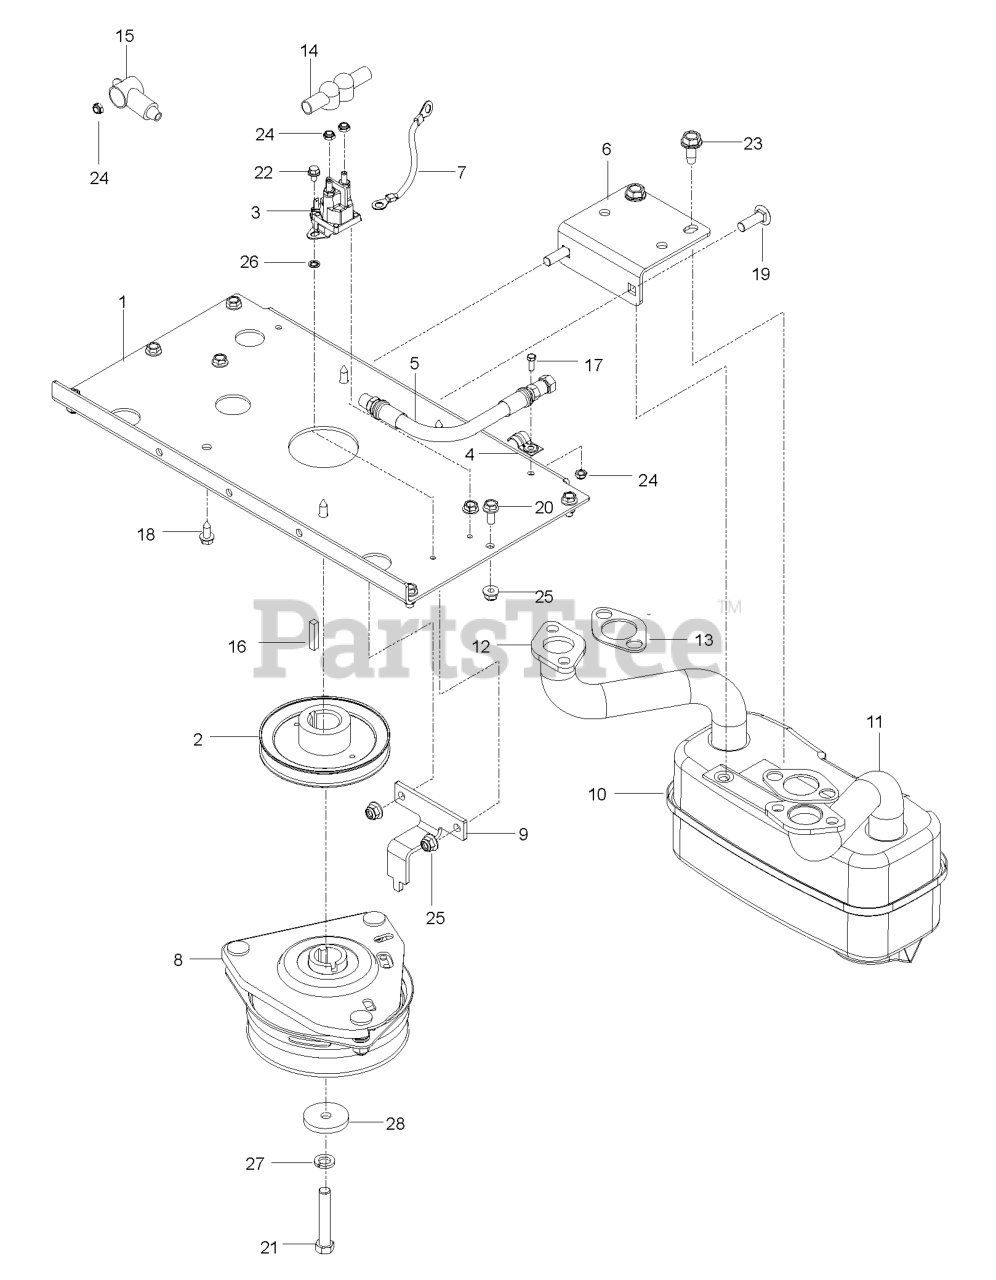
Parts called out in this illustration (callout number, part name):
1	PLATE.PNT.ENGINE.E-DIP
2	PULLEY.DRIVE.XMSN
3	SOLENOID.STARTER.BRASS.PLUNGER
5	HOSE.ASSEMBLY.OIL.DRAIN
6	BRKT, MUFFLER, BLK
7	CABLE POSITIVE
8	CLUTCH MZ ZTR GT.48/54"1.125"
9	BRACKET.CLUTCH.STOP.PNTX431
10	MUFFLER ASM TWIN
11	PIPE.EXHAUST.LH.CV18/20
12	PIPE.EXHAUST.RH.CV18/20
13	GASKET.EXHAUST.KAWASAKI
14	TERMINAL COVER
16	KEY, 1/4 SQ X 1 1/4
17	HCS 1/4-20.
18	SCREW 3/8-16X1
19	RHSSNB 5/16C X 1.0
20	HHFS 5/16-18 X 3/4
21	CLUTCH BOLT7/16-20X2.5 GR596HR
22	HWST 1/4C X 3/8
23	BOLT 5/16-18 X 3/4
24	JAM NUT 1/4C (2 2 PW01)
25	5/16-18 NYLOC FLANGE NUT
26	WASHER 1/4 INT TOOTH
27	WASHER 7/16 LOCK
28	SPINDLE WASHER
